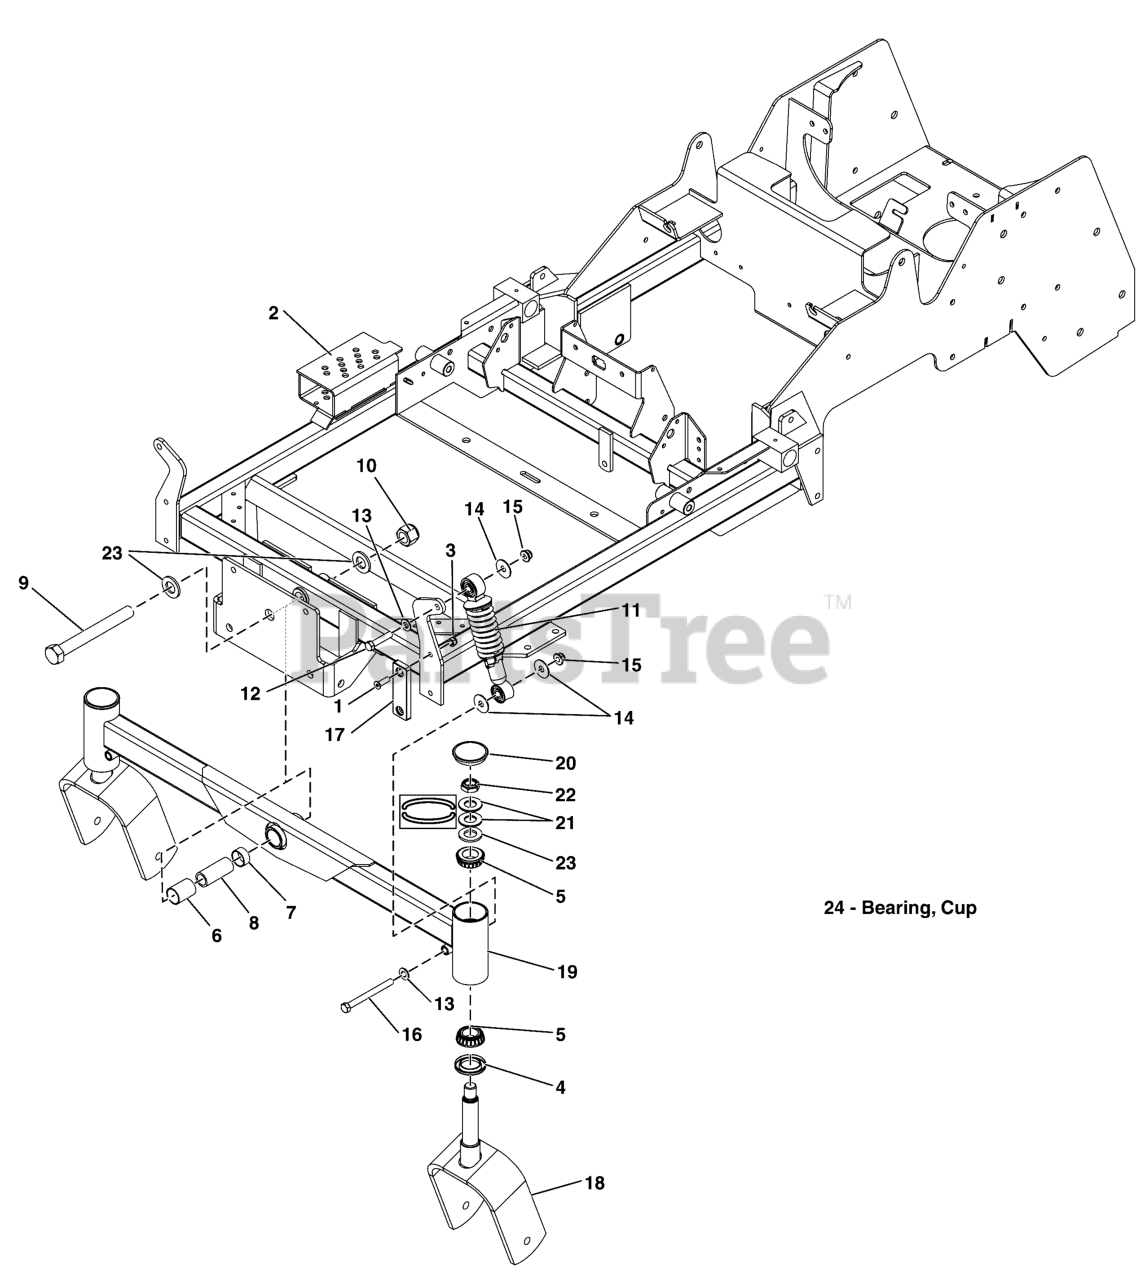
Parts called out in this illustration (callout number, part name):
1	SCREW, 5/16-18 X 1 PHILLIPS HD, BZ
2	WELD, MAIN FRAME, CITATION XT - ORG
3	NUT, Hex Nylock, 5/16-18
4	SEAL, GREASE
5	BEARING, TAPERED ROLLER, 1
6	PIVOT BEARING-1.00 X 1.125 ODX1.50
7	PIVOT BEARING, 1.00 X 1.125 OD X .50
8	SPACER, .75 X 1.00 X 2.38
9	BOLT, 3/4-16 X 6-1/2 YZ GD8
10	NUT, 3/4-16 HEX NYLON LOCK
11	SHOCK, SPRING ASSEMBLY
12	BOLT, 3/8-16 X 1-3/4 GD5
13	WASHER, .406
14	WASHER-3/8 FENDER
15	NUT, Hex Flange, Nylock, 3/8-16
16	BOLT, 3/8-16 X 4 GD5 YZ
17	PAD, FRICTION - 1.25 X 4.00
18	WELD, CASTER YOKE -ORG
18	YOKE, Caster
19	WELD, PIVOTING FRONT END - ORG
20	CAP, LOW PROFILE, STEEL
21	WASHER, BELLEVILLE - 1.500 X .755
22	NUT, 3/4-16, HEX JAM NYLON LOCK
23	WASHER, 3/4 SAE
24	BEARING, CUP
